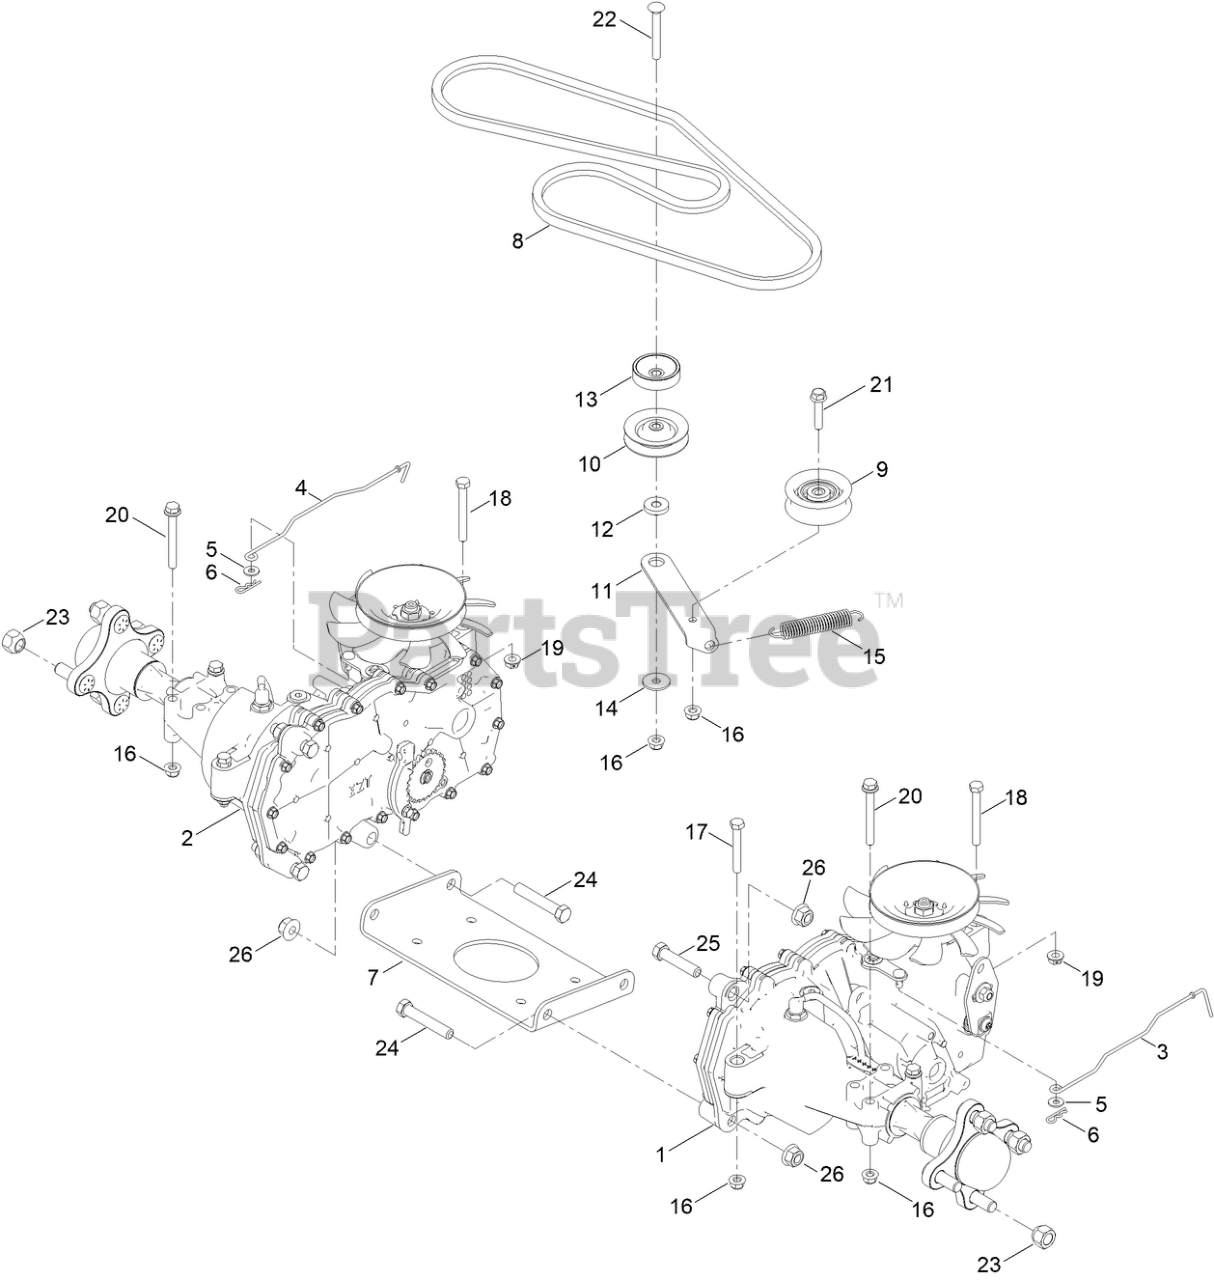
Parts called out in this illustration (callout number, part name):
1	LH HYDRO TRANSAXLE ASM
2	RH HYDRO TRANSAXLE ASM
3	ROD-BYPASS, LH
4	ROD-BYPASS, RH
5	WASHER
7	PLATE-CROSS HYDRO
8	V-BELT (A SEC 63.8 EL)
9	PULLEY-IDLER, FLAT
11	ARM-IDLER
12	SPACER-IDLER ARM
13	SPACER
14	WASHER-PIVOT
15	SPRING-PEDAL, RETURN
16	NUT-HF, NI
17	SCREW-HH
18	SCREW-HH SPCL
19	NUT-HF
20	SCREW-HHF
21	SCREW-HHF
22	SCREW-CARR
23	NUT-LUG
24	SCREW-HH
25	SCREW-HH
26	NUT-HF, NI
